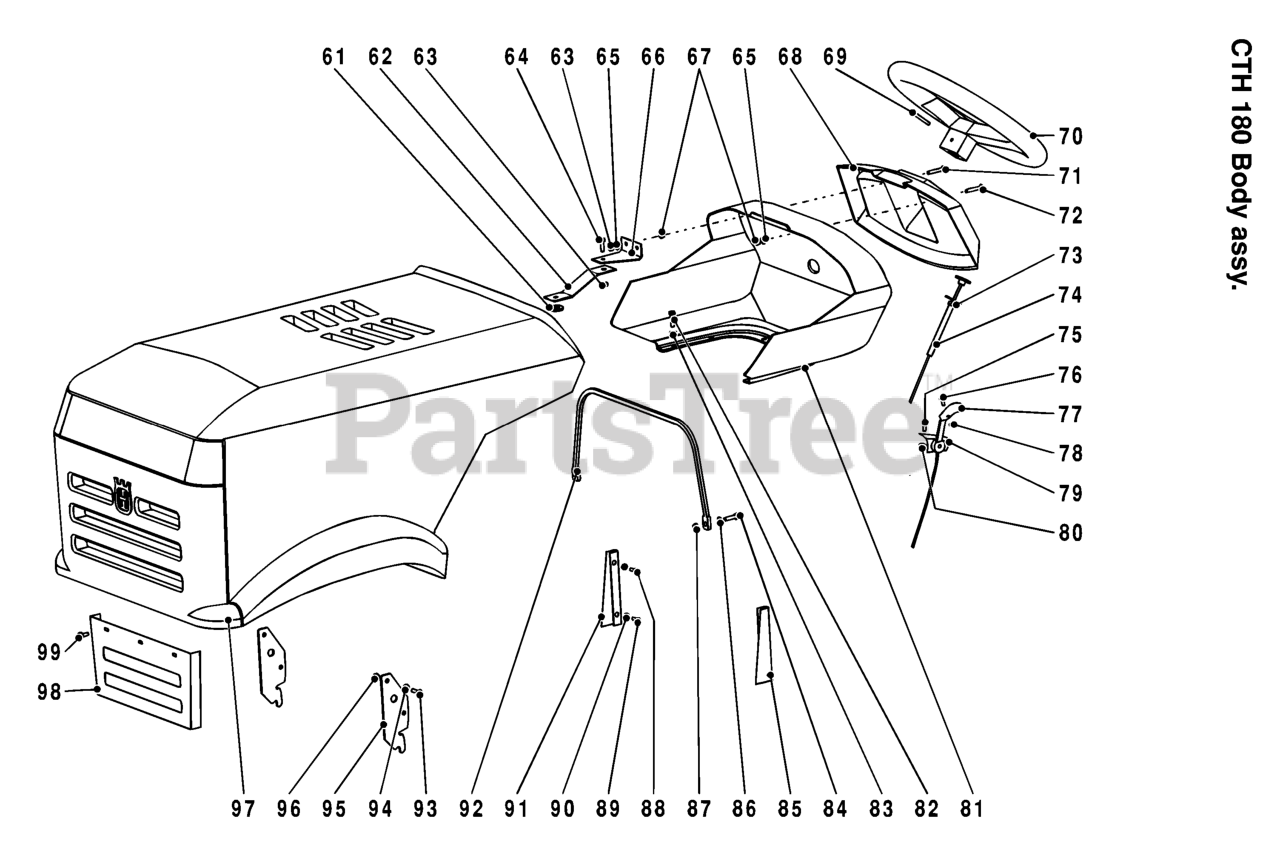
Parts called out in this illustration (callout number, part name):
63	Blocking nut M 6 Z
64	BOLT FLANGE - M6X20
65	WASHER - M6
67	Blocking nut M 6 Z
70	STEERING WHEEL
72	SCREW
73	NUT
74	CHOKE CONTROL
76	SCREW MCS 5X16
78	NUT M6M M4
79	THROTTLE TRIGGER
90	NUT M6M M4
94	Washer 0 5.3
96	NUT.CROWNLOCK.1/4
98	HEAT SHIELD
